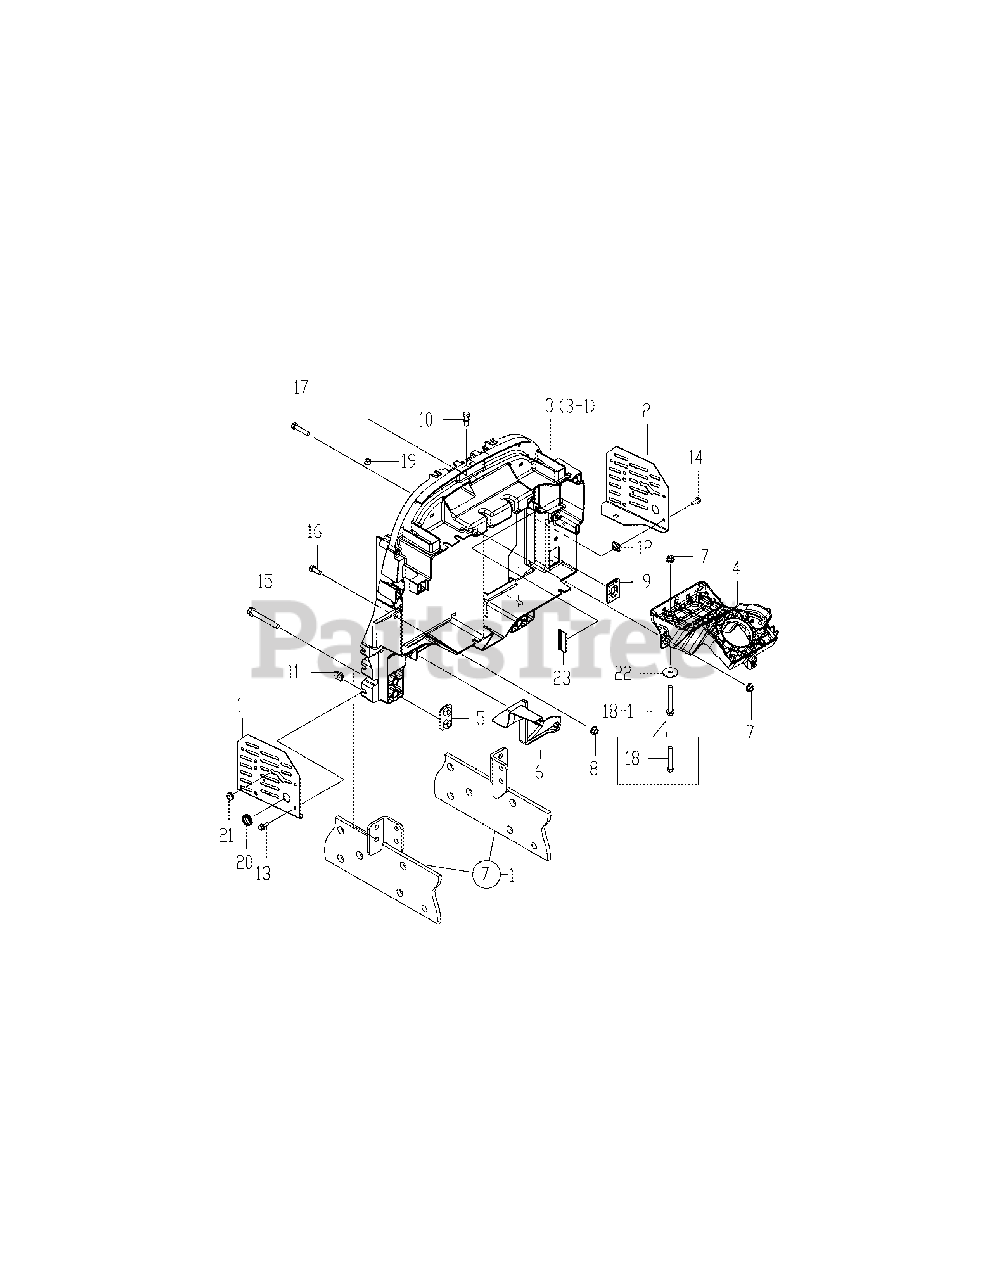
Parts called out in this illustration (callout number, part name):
1	Cover Assy, LH, Fan Belt
2	Cover Assy, RH, Fan Belt
3	Bracket, Column
3-1	Bracket, Column
4	Bracket, Steering
6	Boot, Dashcover
9	Grommet, Harness
18-1	Bolt M 8X 65 Plated
20	Grommet, 16.0 X 2
22	Washer, 9X32X3.2
23	Seal, Fender
